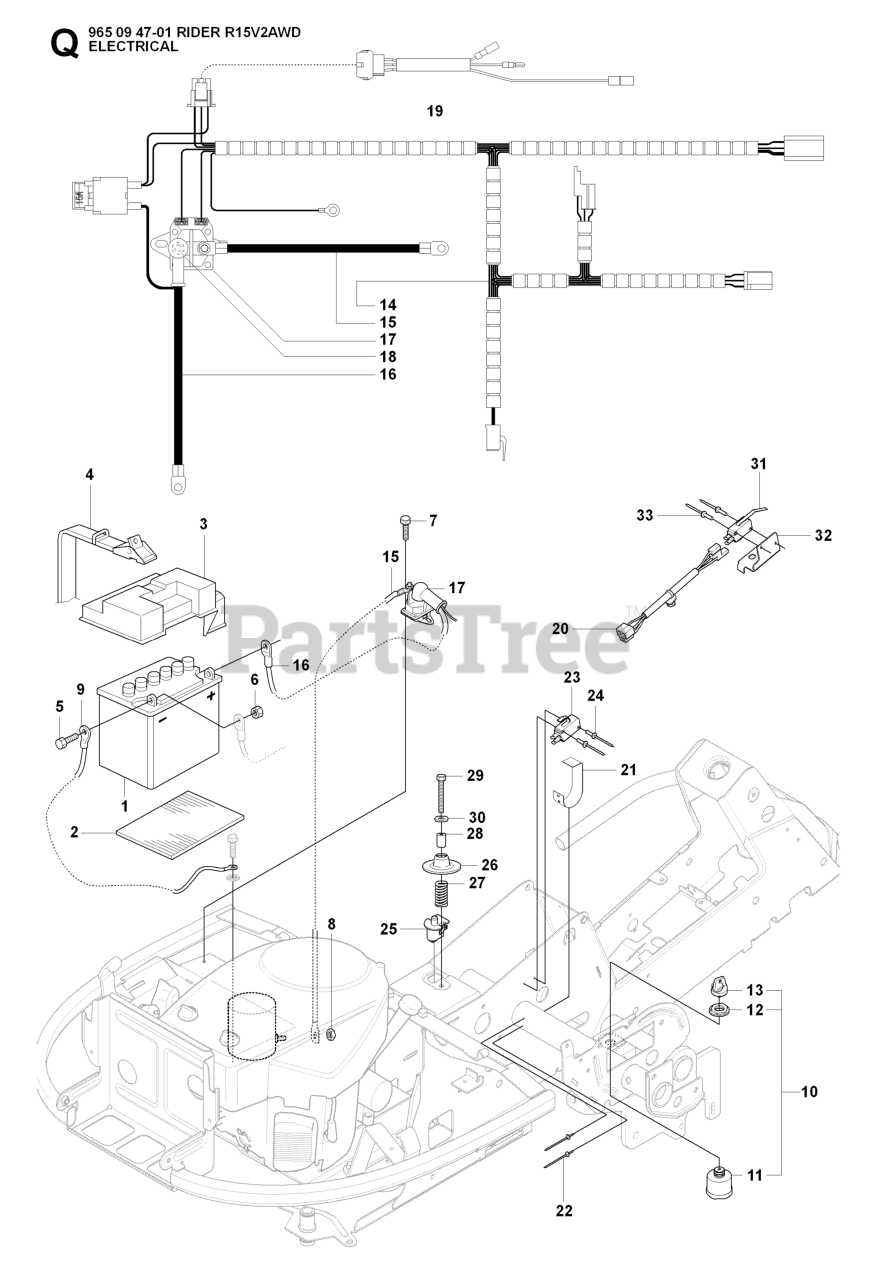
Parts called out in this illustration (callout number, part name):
1	BATTERY - DRY
10	IGNITION SWITCH
11	IGNITION SWITCH
13	IGNITION KEY
20	WIRING
23	%BRAKER
28	SPACER TUBE
29	SCREW
30	WASHER BRB 8.4X17
31	RP MICRO SWITCH
